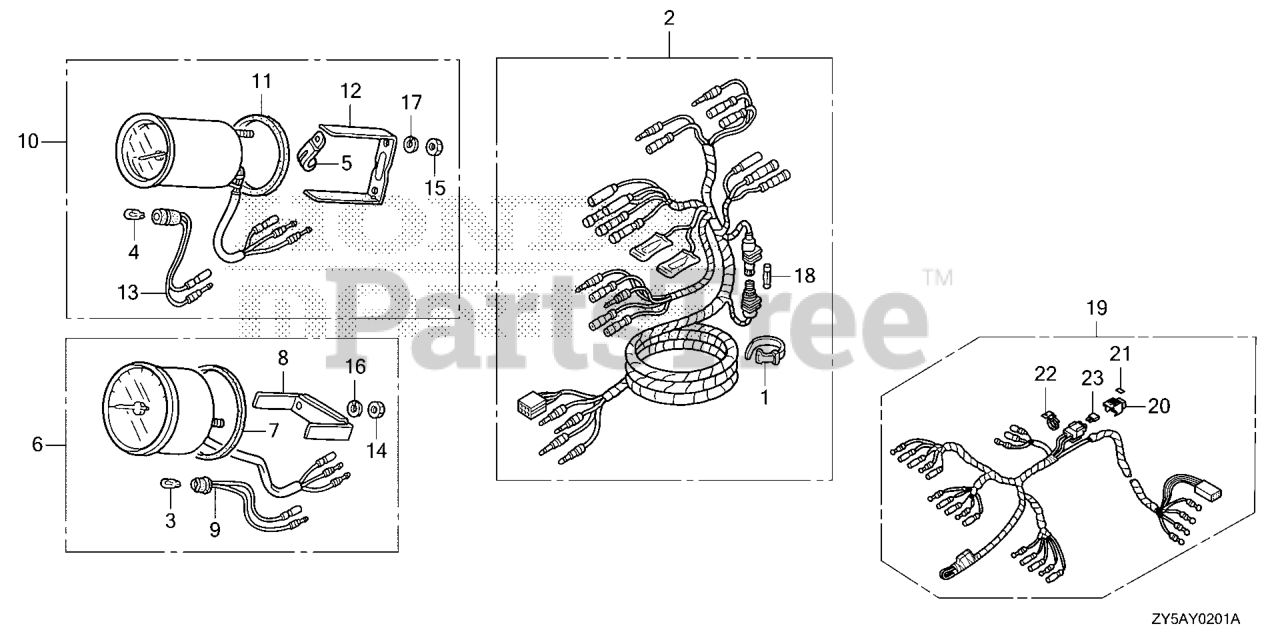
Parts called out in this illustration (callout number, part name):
1	BAND B1, CABLE Use up to Frame SN 1001879.
2	HARNESS ASSY., METER (A)
3	BULB, WEDGE BASE (T10) (12V 1.7W) (STANLEY)
4	BULB, WEDGE BASE (12V1.7W) (TOSHIBA)
5	CLAMP
6	TACHOMETER ASSY.
9	SOCKET (TO 1015209) (FROM 1015210)
10	METER ASSY., TRIM
11	GASKET (TO 1015209) (FROM 1015210)
12	BRACKET (TO 1015209) (FROM 1015210)
13	SOCKET (TO 1015209) (FROM 1015210)
15	NUT, HEX. (4MM)
17	WASHER, SPRING (4MM)
18	FUSE A (10A)
19	HARNESS ASSY., METER (A)
20	COVER ASSY., FUSE
21	LABEL, FUSE (10A)
22	HOLDER, CONNECTOR (128.6MM) (NATURAL)
23	FUSE, MINI (10A)
